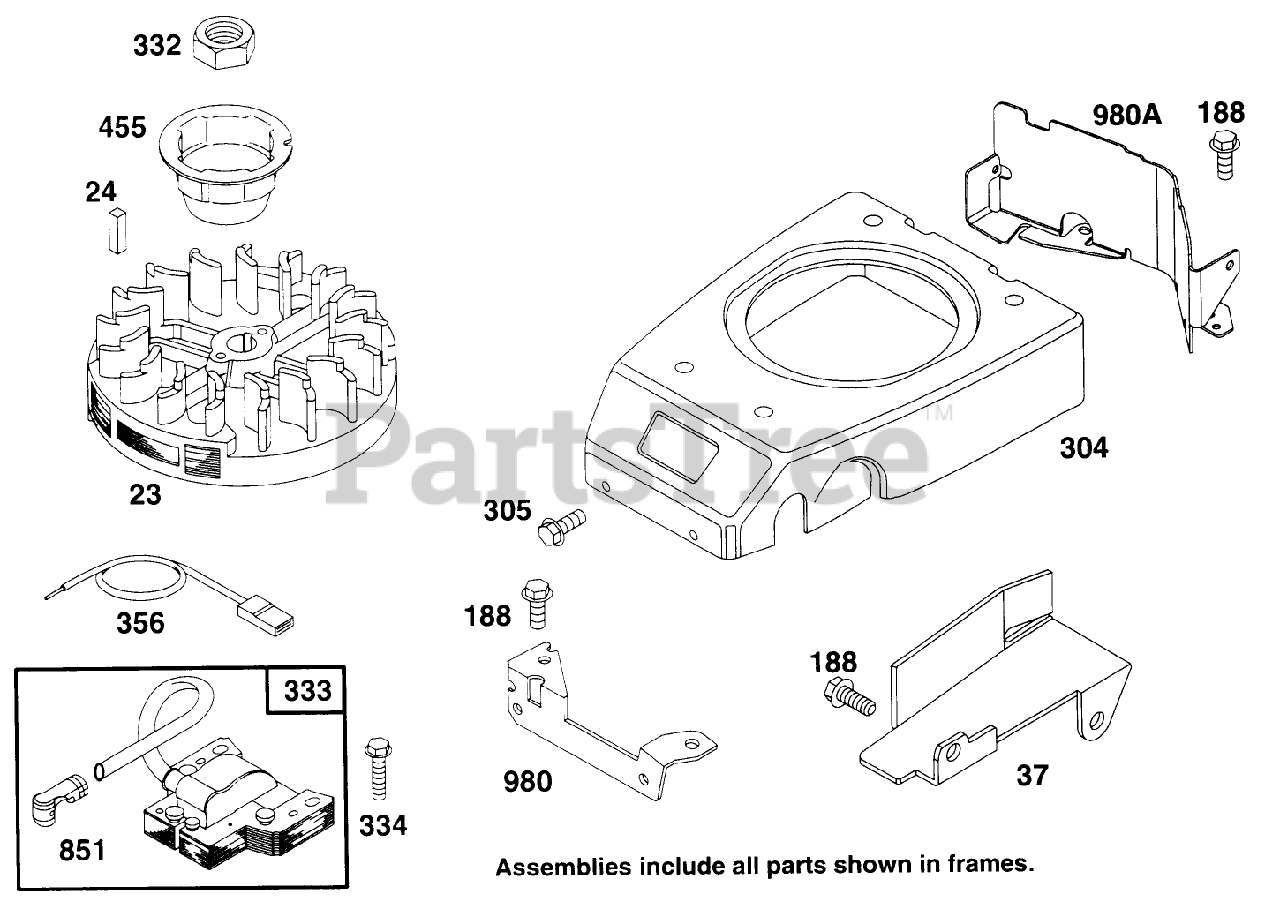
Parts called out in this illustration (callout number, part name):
24	KEY - FLYWHEEL
188	SCREW - HEX HEAD
304	BLOWER HSG ASM
305	SCREW - HEX HEAD
332	NUT - HEXAGON
356	WIRE - GROUND
980A	BLOWER HSG BRACKET
